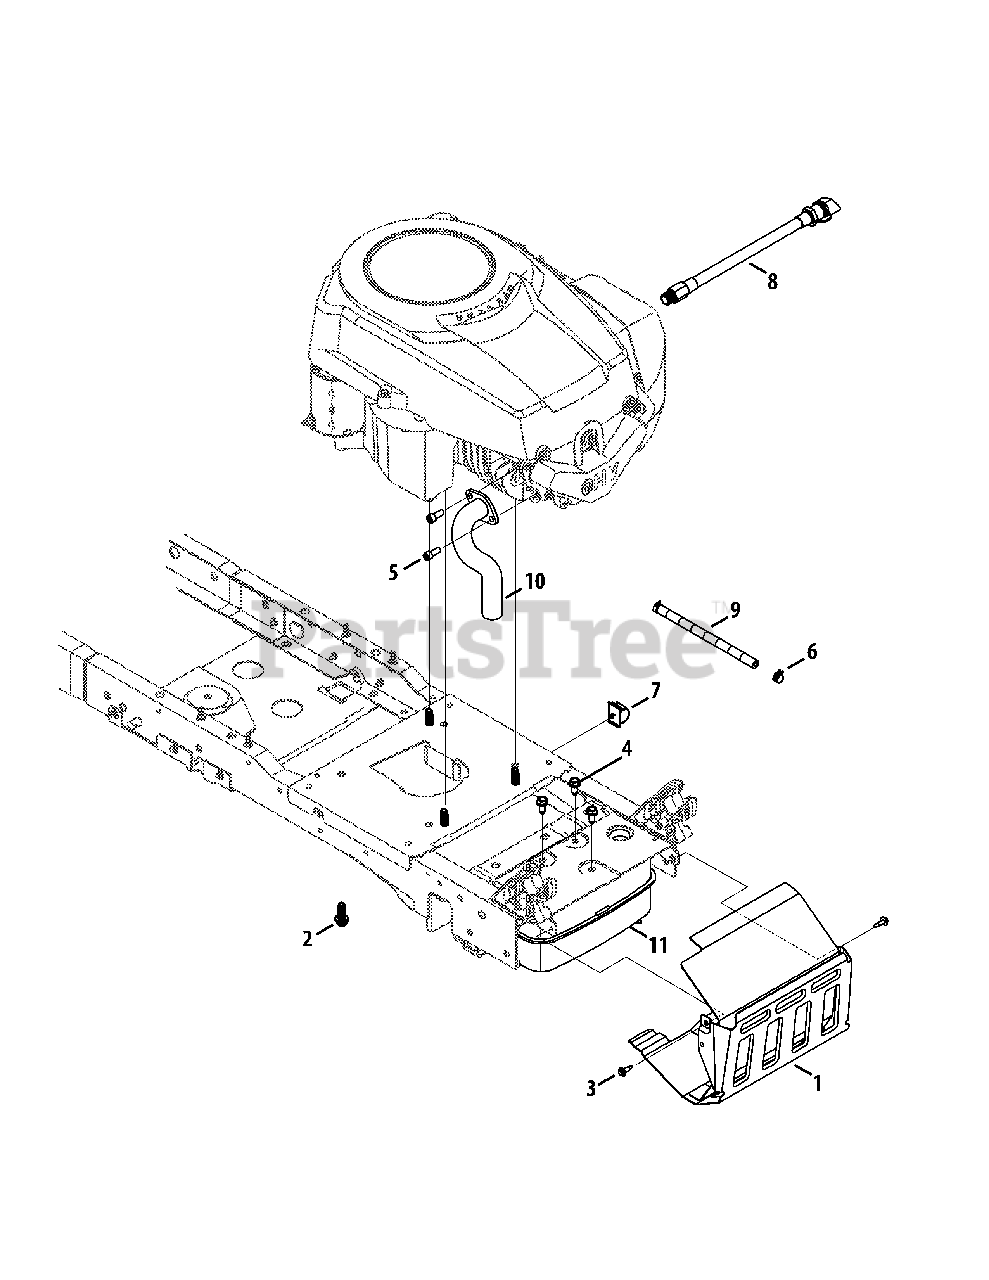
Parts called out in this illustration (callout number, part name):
1	Shield Ass’y, Muffler
2	Screw, Self-tapping, 3/8-16, 1.0
3	Screw, M6-1 x .625
4	Screw, Self-tapping, M8-1.25, .750
5	Screw, Sokt Head, 5/16-18, .750
6	Clamp, Hose, .490 Dia.
7	Push Mount Wire Clip, .750
8	Drain, Oil
9	Hose, Fuel, Low Permeation, 1/4
10	Exhaust Pipe
11	Muffler, Kohler
